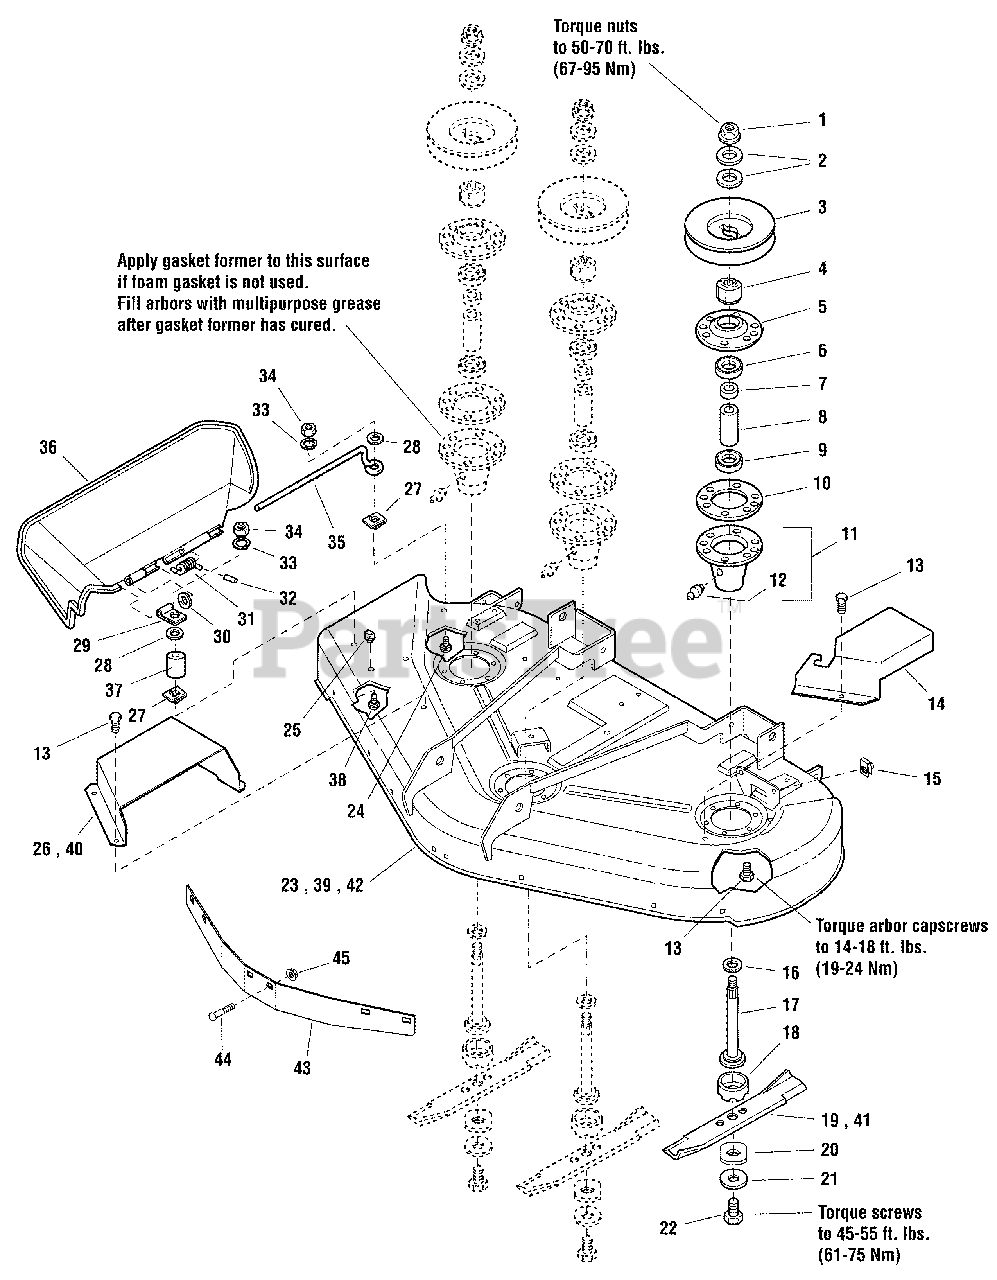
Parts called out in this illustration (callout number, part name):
1	NUT, HEX FLANGE, 9/16-18
2	WASHER, BELLEVILLED, 9/16
5	COVER, ARBOR HOUSING
6	BEARING, BALL, 3/4 X 1-3/4 X 5/8
7	SPACER, 21/32 X 3/4 X 5/8
8	SPACER, 11/16 X 5/32 X 2-11/16
9	BEARING, BALL, 11/16 X 1-9/16 X 15/32
11	ARBOR HOUSING ASSEMBLY
12	FITTING, GREASE
13	SCREW-HEX WSHR HD TAPTT5/16-18X0.750BLK
14	GUARD, BELT - LH - ORG
15	BODY CLIP, 5/16-18 X 1/2" DEEP
16	WASHER, 9/16, BLACK
17	SHAFT, ARBOR
18	SHIELD, GRASS, LOWER
19	BLADE, Mower, 16-1/8
20	WASHER, HEX, 11/16 X 2
21	WASHER, SPRING, 15/32, BLACK
22	BOLT, 7/16-14 X 1-1/4
23	DECK SHELL W/ DECALS
24	BOLT-RD HD SH SQ NK 1/4-20X0. 875 G5 BLK
26	GUARD, BELT - RH, 44", SMI ORANGE
27	NUT-PUSH FOR .250 DIA THREAD .500 OD BLK
28	WASHER-0.250(0.26IDX0.84ODX.12THK) BLK
29	CLAMP, WIRE, .312DIA. (1) .281HOLE BLK
30	WASHER-0.312 (0.34IDX0.75ODX.06THK) BLK
31	SPRING, TORSION, CHUTE, 44/50
33	LOCKWASHER, SPRING .250 BLK
34	NUT-HEX 1/4-20 BLK 588514
35	ROD, DEFLECTOR
36	DEFLECTOR, BLACK
37	SPACER-0.328IDX0.499ODX0.625LG PM
38	BOLT, CARRIAGE, 1/4-20 X 1.25, GD5,BLACK
39	DECK SHELL W/ DECALS
40	GUARD, BELT, RH
41	BLADE, MOWER, 18-1/8
42	DECK SHELL W/ DECALS
43	BAFFLE - FRONT 44/50 - BLACK
44	BOLT, 5/16-18 X 3/4 CARRIAGE
45	NUT, 5/16-18 HEX NYLOCK FLANGE
